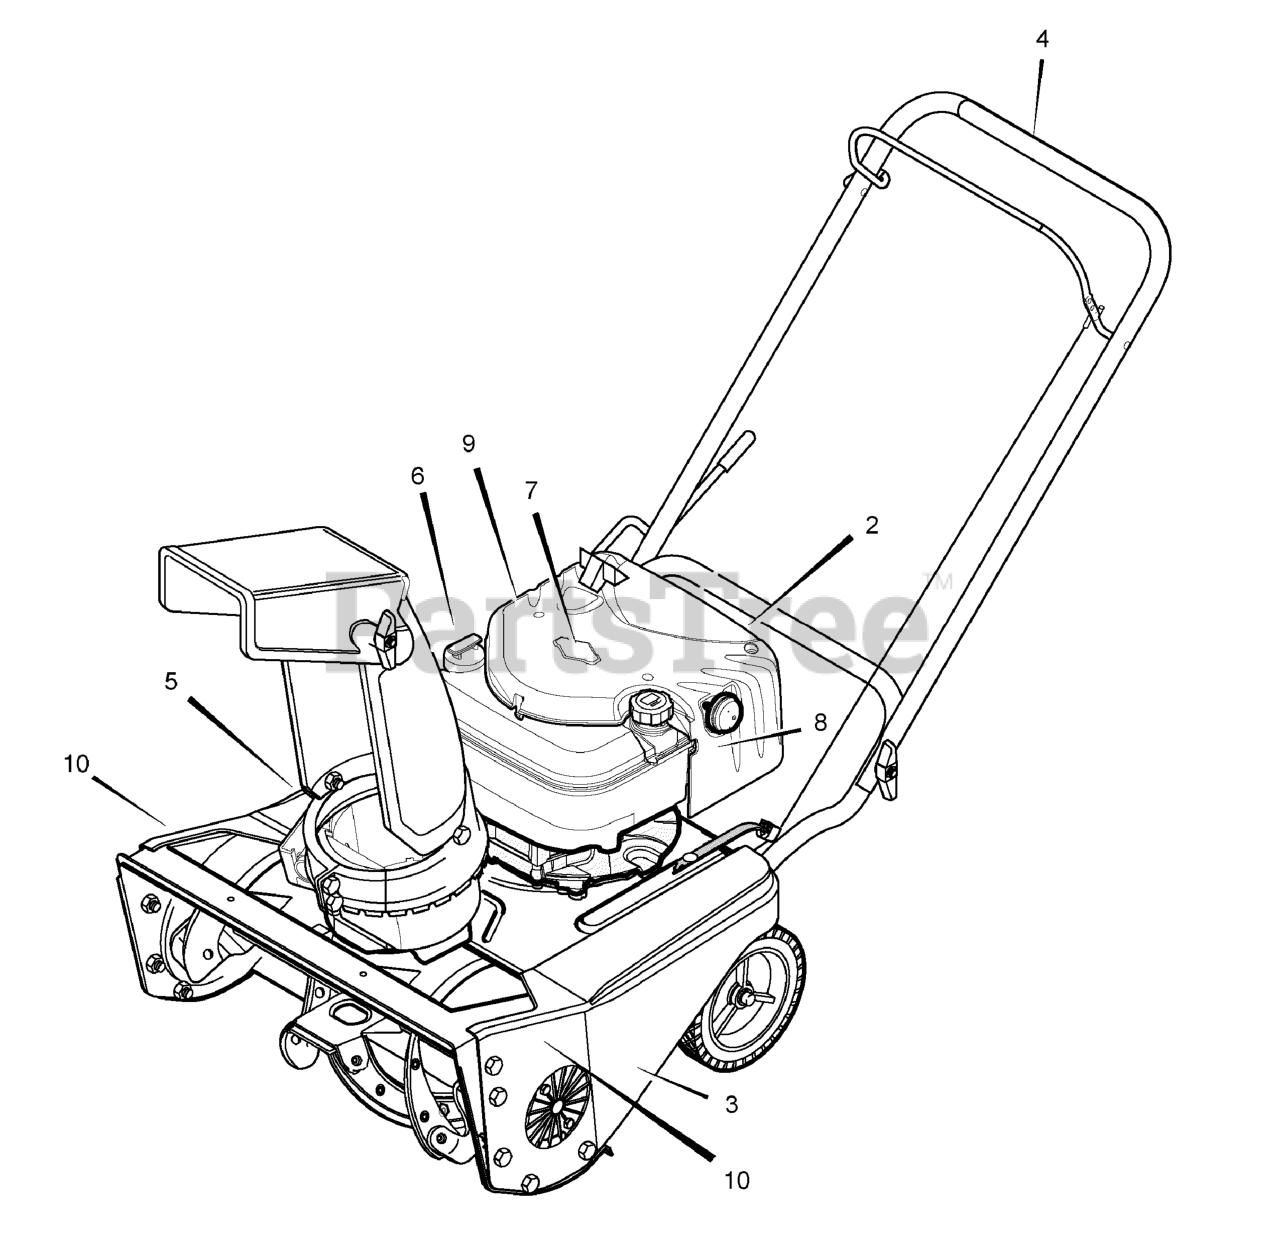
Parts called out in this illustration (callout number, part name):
2	Decal, Choke
3	Decal, Belt Instruction (Inside Cover)
4	Decal, Auger Engage
5	Decal, Danger Auger (Foot)
6	Decal, Danger Chute (Hand)
7	Decal, Briggs & Stratton
8	Decal, Primer Bulb
9	Decal, Hot Surface
10	Decal, Partner 0625/21
